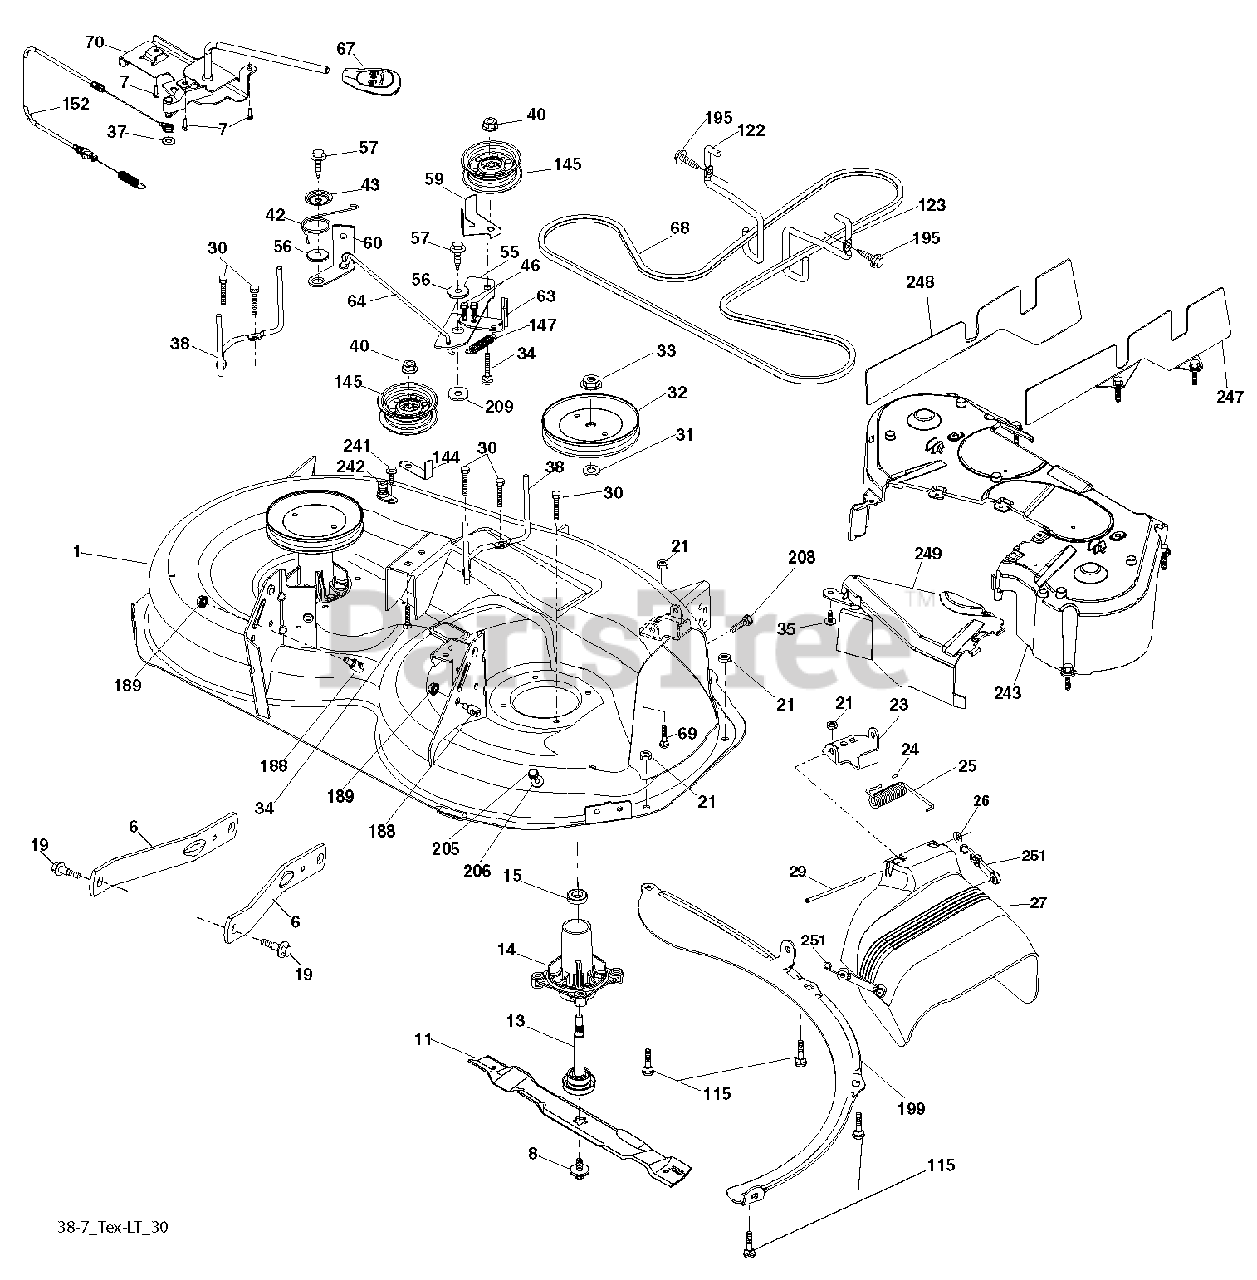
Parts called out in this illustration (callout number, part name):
1	DECK.WELD.38.NGW.TX.W/HOL.GREY
6	ARM.SUSPENSION.MOWER.R
7	SCREW.#10 X 0.750.BOS
8	BOLT.WASHER.ASM.7/16-2
11	BLADE 38" PREMIUM
13	SHAFT.ASM.MDRL.N/GREASE.38
14	HOUSING.MANDREL.4PT.
19	BOLT.SHOULDER
21	LOCKNUT
23	BRKT.DEFLECTOR.38"2005+
24	CAP-SLEEVE LT
25	SPRING.TORSION.DEFLECT
26	NUT PUSH M
27	SHIELD ASM.DFLCTR MWR.38-7"BLK
29	ROD.HINGE
30	SCREW, WASHER HEAD
31	WASHER.SPACER.MANDREL
32	PULLEY.MANDREL.5.0.PD.38"
33	NUT.FLANGE.LOCK.TOP
34	BOLT.3/8-16X1.50
35	FASTENER.XMAS.TREE
37	WASHER
38	KEEPER BELT LH MANDREL
40	NUT LOCK FLG 3/8-16 UNC
42	SPRING.TORSION.BRAKE
43	SRPING.TORSION.RETAINE
46	SCREW.1/4-20X5/8
56	SPACER.RETAINER
57	SCREW 3/8-16X1
59	GUARD, BELT
60	ARM BRAKE MOWER RH 38"
63	RP ARM.BRAKE.MOWER.38"LH.TEX
64	LINK BRAKE
67	HANDLE.CLUTCH.CABLE.LT
69	BOLT
70	CLUTCH.ASM.MANUAL.LT.PRED
115	BOLT
122	KEEPER BELT ENGINE LH
123	KEEPER BELT RH
144	KEEPER BELT
145	PULLEY.IDLER.48"PRIMARY
147	SPRING RETURN
152	CABLE.CLUTCH.MANUAL.
188	STUD.FASTNER.W/ANTI-ROTATE
189	NUT LOCK HEX FLANGE 5/16-18
195	SCREW, 3/8-16X3/4
199	BAFFLE.VORTEX.FRONT.38"
206	Washer, 9/32 X 7/8 X 16 Gauge
209	WASHER 12/32X2X10GA
241	SCREW.TT.#10-32X.5.3/8.FLANGE
242	PORT.WASHOUT
247	SHIELD DECK RIGHT
248	SHIELD DECK LEFT
249	COVER CABLE CLUTCH
251	ELASTIC STRAP KIT
